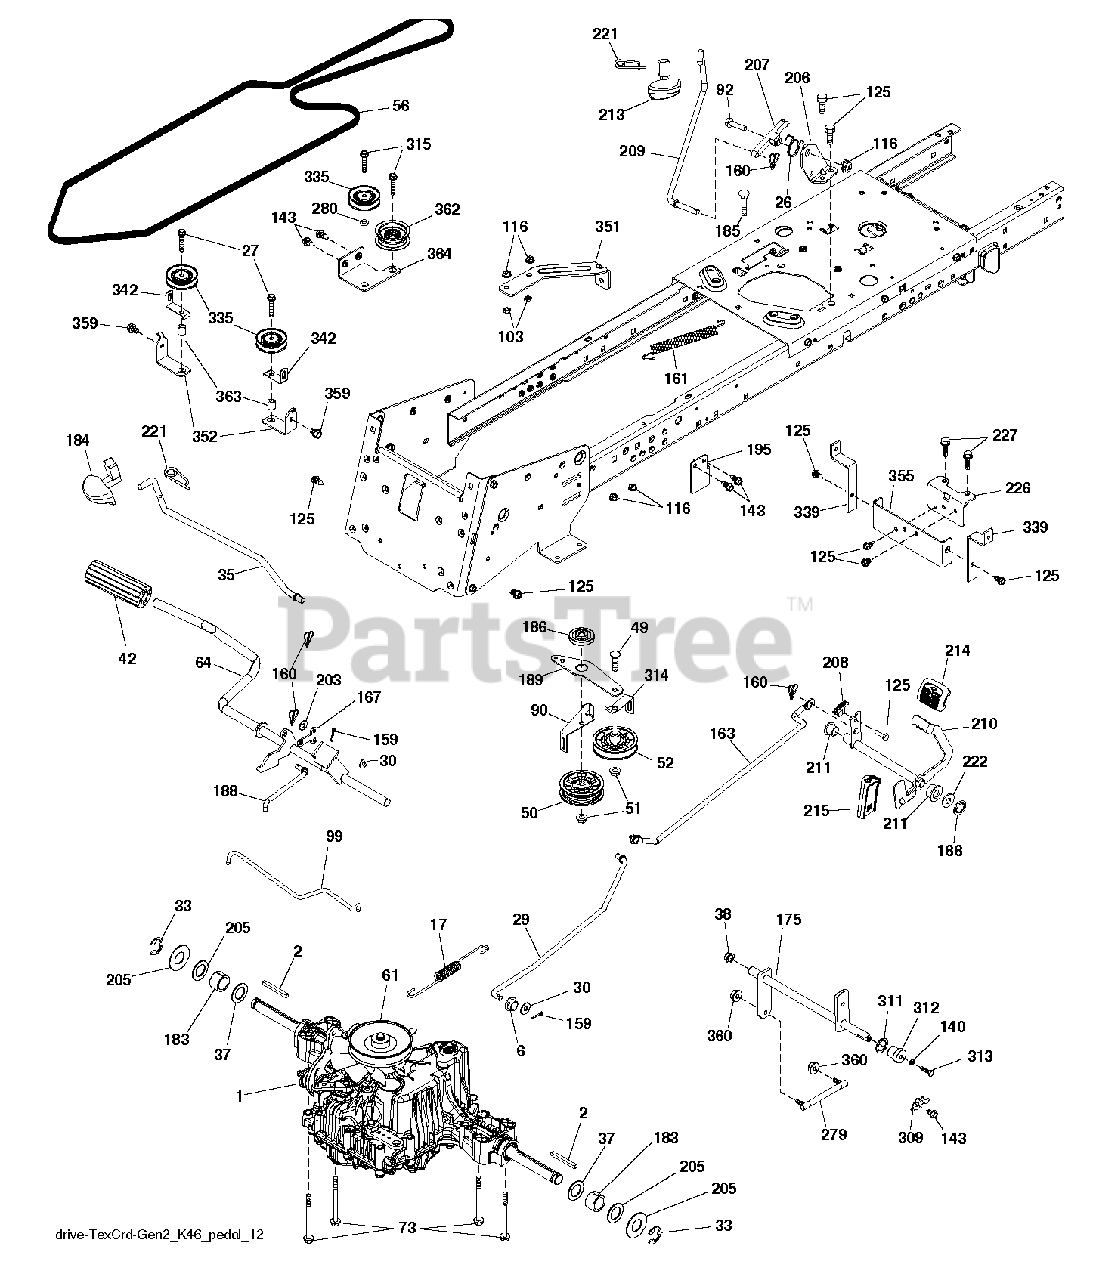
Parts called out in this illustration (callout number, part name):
2	SQUARE KEY
6	GROMMET T
26	SPRING.RETURN.CRUISE
33	E-RING LT
35	Parking Brake Rod, GT Husq
37	WASHER.HARDENED
38	NYLINER SNAP 5/8" ID
42	PEDAL COVER T
49	BOLT
50	IDLER.FLAT.910.OFFSET
51	NUT LOCK FLG 3/8-16 UNC
52	IDLER.V-GROOVE.910.OFFSET
64	SHAFT.ASM.PEDAL.BRK.CNTR
73	BOLT HEX 5/16-18 GR 5
92	BOLT
103	JAM NUT TI
116	NUT LOCK HEX FLANGE 5/16-18
125	SCREW
140	LOCKWASHER
159	COTTER PIN
160	RETAINER CLIP
161	SPRING, RETURN LT
166	NUT.PUSH.625
167	LATCH.BRAKE.SPRING
183	SPACER AXLE
184	HANDLE.PARKG.BRK.HUSQ/PRED.667
186	SPACER.RETAINER
188	LINK.CLUTCH.GROUND.DRIVE
203	WASHER
207	LATCH.CONTROL.CRUISE
208	GEAR.SECTOR.CONTROL.CR
209	ROD.CONTROL.CRUISE.GT.
210	ROCKER.ASM.PEDAL.CONTR
211	BEARING.NYLON
213	KNOB.CONTROL.CRUSIE.HU
214	PAD PEDAL FORWARD
221	RETAINER.SPRING.CLIP.H
222	WASHER 21/32 X 1-1/4 X 10 GA.
226	BRACKET.MOUNT.TORQUE.K46.TLT
227	SCREW
309	PLATE FASTENING LT
311	WASHER NYL
315	BOLT.5/16-18X1.25
335	PULLEY.V-IDLER.
359	SCREW LT.3/8-46X5/8
